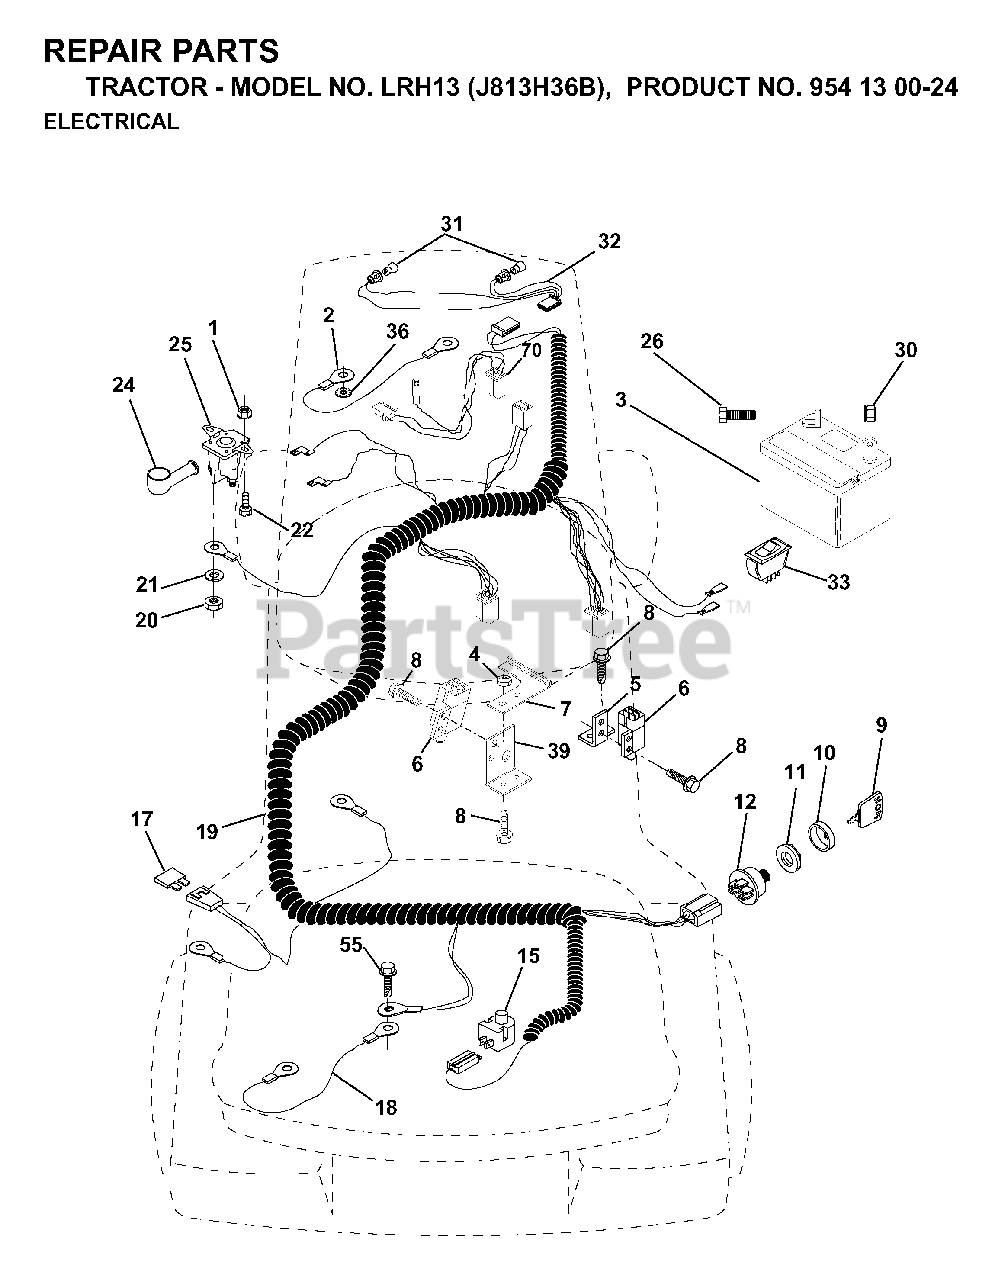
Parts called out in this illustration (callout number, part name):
2	CABLE ASM
5	BRACKET LT
6	SWITCH INTERLOCKT
7	KEEPER, ACTUAT. L.R.
9	KEY MLD GEN DELTA
10	COVER SWITCH KEY
11	NUT, IGNITION
12	IGNITION SWITCH
15	SWITCH SEAT
19	HARNESS IGN LR NLA
20	NUT
21	LOCKWASHER
24	TERMINAL COVER
25	SOLINOID
30	NUT
31	LIGHTBULB
32	HARNESS LIGHT SOCKET
33	SWITCH LT
36	LOCKWASHER
70	HARNESS, ENGINE
